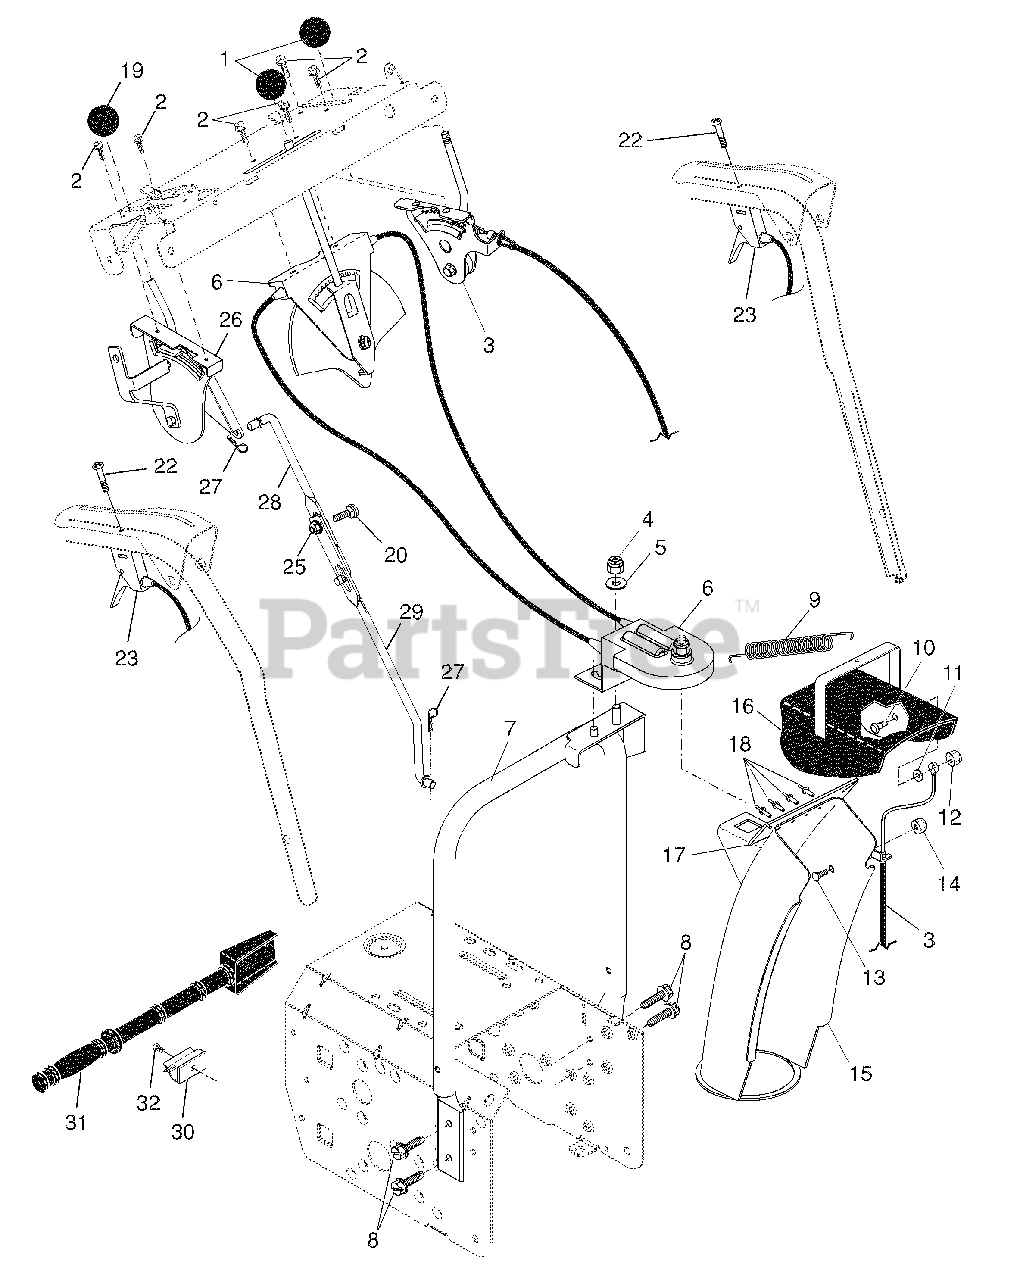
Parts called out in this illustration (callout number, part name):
1	Knob, Lever
2	Screw #10-24 x 5/8
3	Control Assembly, Deflector
4	Nut, Lock 3/8-16
5	Washer, Flat 3/8
6	Control Assembly, Chute Rotater
7	Support, Pivot
8	Screw, Hex Head 5/16-18 x 3/4
9	Spring, Deflector
10	Bolt, Shoulder
11	Washer, Friction, Nylon
12	Nut, Lock 1/4-20
13	Bolt, Carriage 5/16-18
14	Nut, Lock 5/16-18
15	Chute Assembly
16	Deflector Assembly
17	Seal, Deflector
18	Rivet, Blind
19	Knob, Speed Control Lever
20	Bolt, Carriage 5/16-18 x 3/4
22	Screw #10-24 x 1-1/2
23	Control Assembly, Power Steering
25	Nut, Lock 5/16-18
26	Lever Assembly, Speed Control
27	Retainer, Hairpin
28	Rod, Upper, Speed Control
29	Rod, Lower, Speed Control
30	Clip, Clean-Out Tool
31	Tool, Clean-Out
